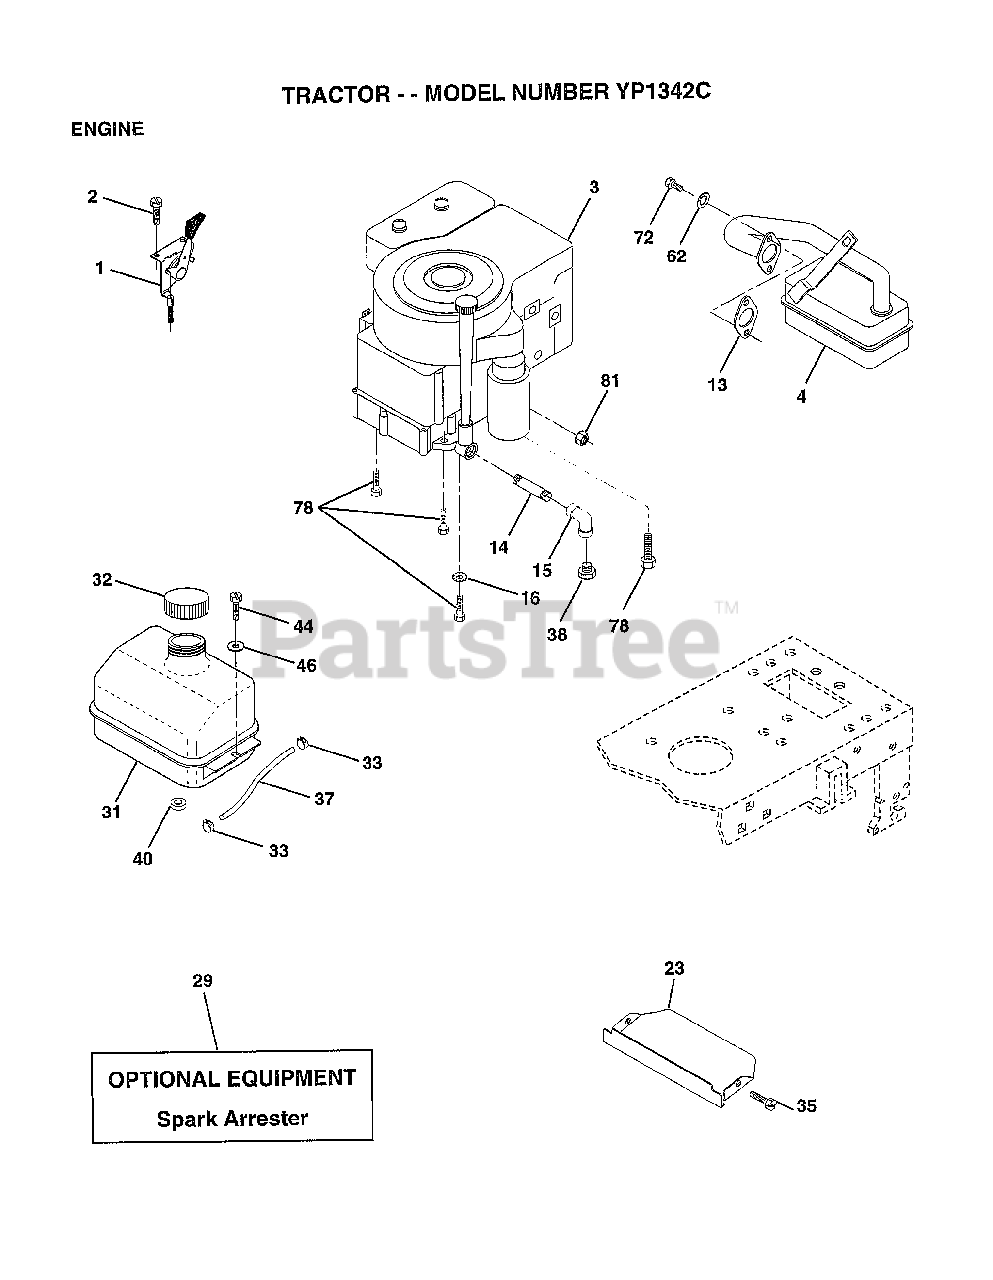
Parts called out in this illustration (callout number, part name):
1	CONTROL THROTTLE
2	SCREW LT
4	MUFFLER
13	GASKET ENG 1 313 LD TIN PLATED
14	PIPE NIPPLE
15	ELBOW
16	LOCKWASHER
23	SHIELD.BRN/DBR.GD
31	TANK.FUEL.LT.
32	CAP ASM FUEL
33	HOSE CLAMP
35	SCREW
37	LINE FUEL
44	SCREW HEX CRT
46	WASHER
62	LOCKWASHER
72	SCREW
78	SCREW
81	NUT
